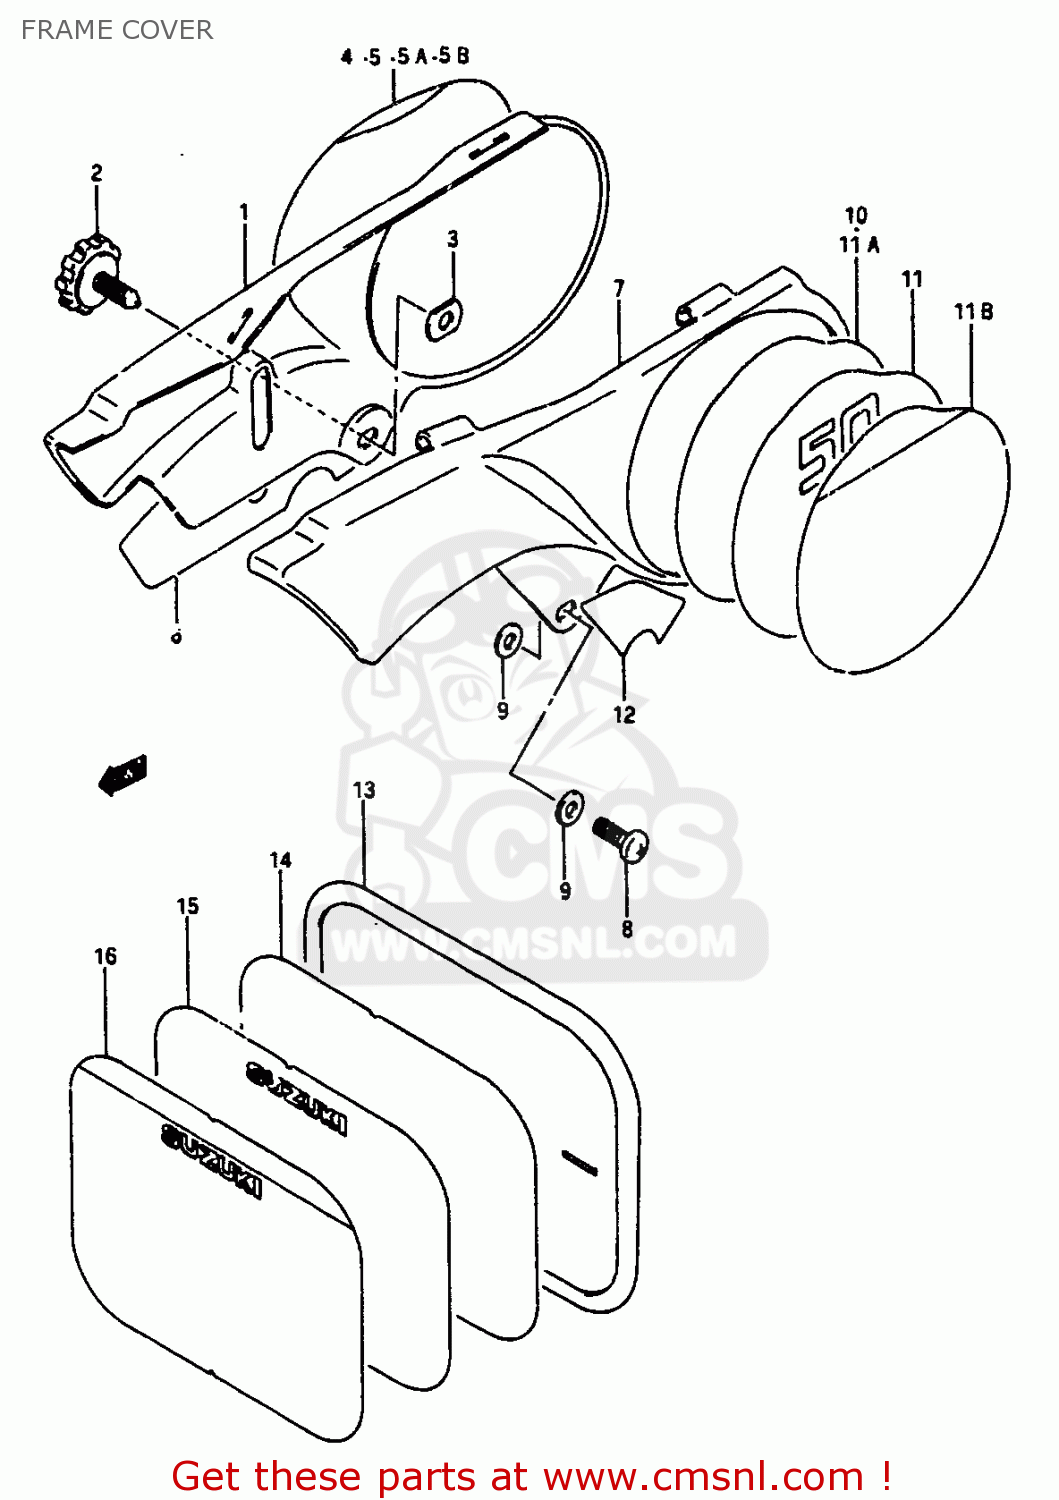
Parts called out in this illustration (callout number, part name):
1	COVER,FRAME,RIGHT
2	KNOB,FRAME COVER,R
3	NUT
4	EMBLEM
5	EMBLEM
5A	EMBLEM
5B	TAPE,FRAME COVER,RIGHT
6	EMBLEM,FRAME COVER,R LWR
7	COVER,FRAME,LEFT
8	SCREW 6X12
9	WASHER
10	EMBLEM,FRAME COVER
11	EMBLEM,FRAME COVER
11A	EMBLEM,FRAME COVER,LEFT,REAR
11B	TAPE,FRAME COVER,LEFT
12	EMBLEM,FRAME COVER,L LWR
13	PLATE,NUMBER FR
14	EMBLEM,FRONT NUMBER PLATE
15	EMBLEM,FRONT NUMBER PLATE
16	EMBLEM,FRONT NUMBER PLATE
